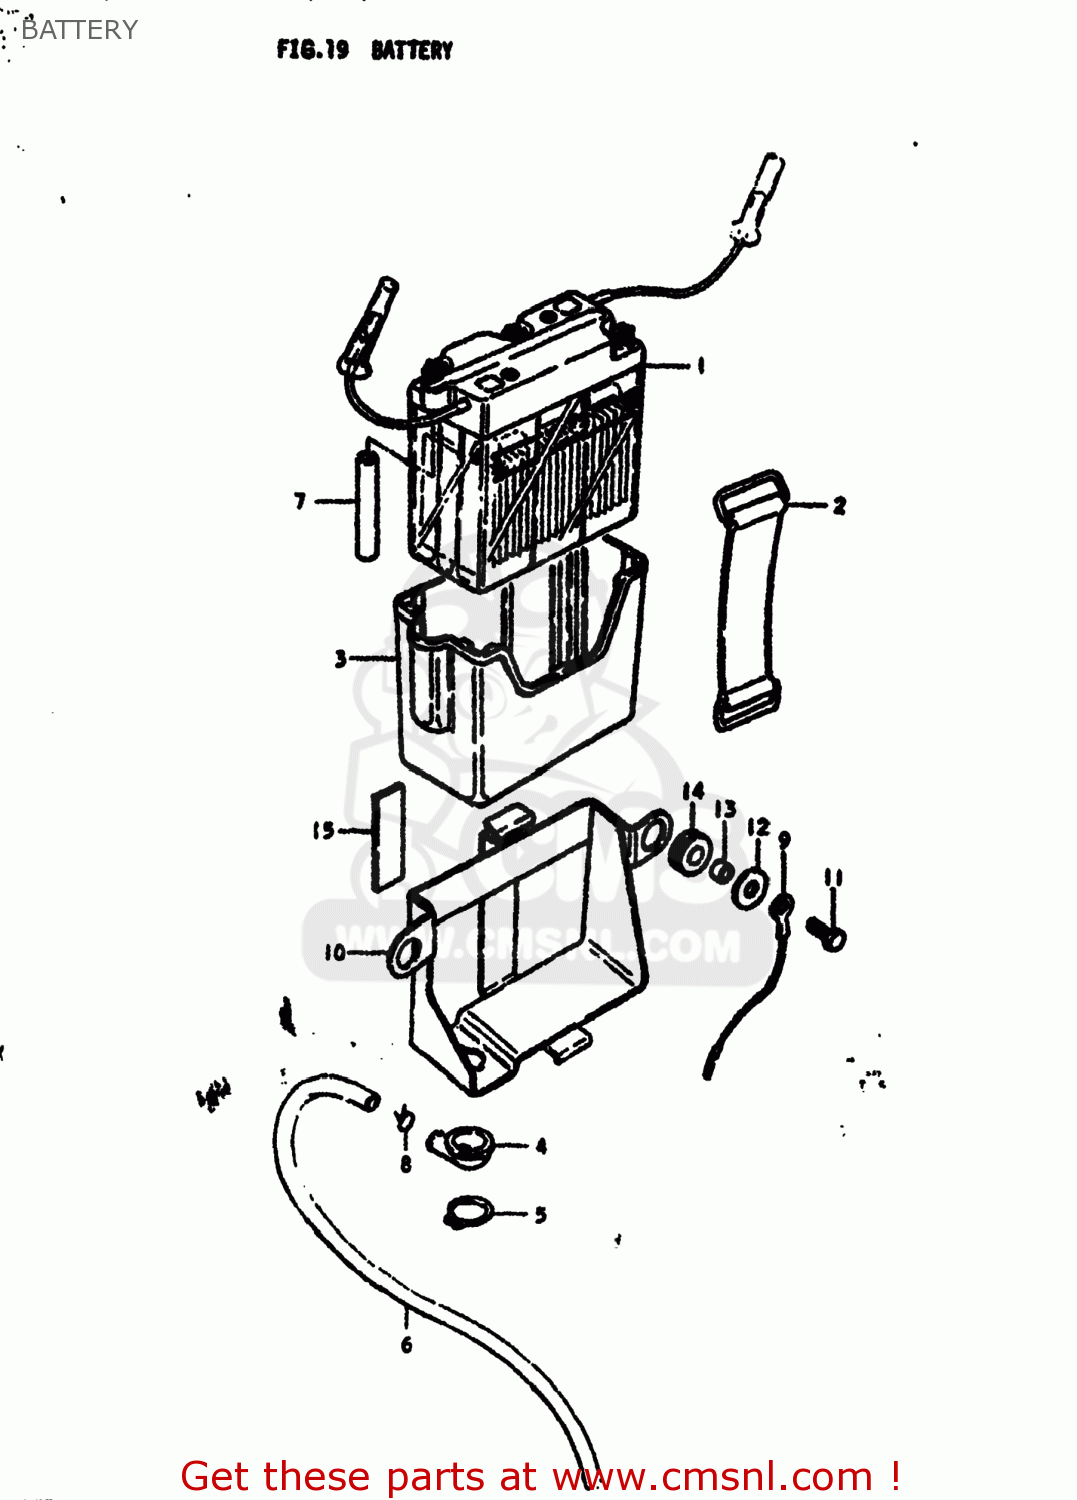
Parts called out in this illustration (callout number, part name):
1	BATTERY ASSEMBLY
2	BAND
3	CASE,BATTERY
4	FUNNEL,BATTERY EXHAUST
5	CIRCLIP
6	HOSE,BATTERY EXHAUST
7	HOSE, EXHAUST (L:45)
8	CLIP
9	LEAD WIRE
10	HOLDER,BATTERY
11	BOLT
12	WASHER (6.5X20X1.2)
13	SPACER (7X9X7)
14	CUSHION
15	PROTECTOR,20X9
